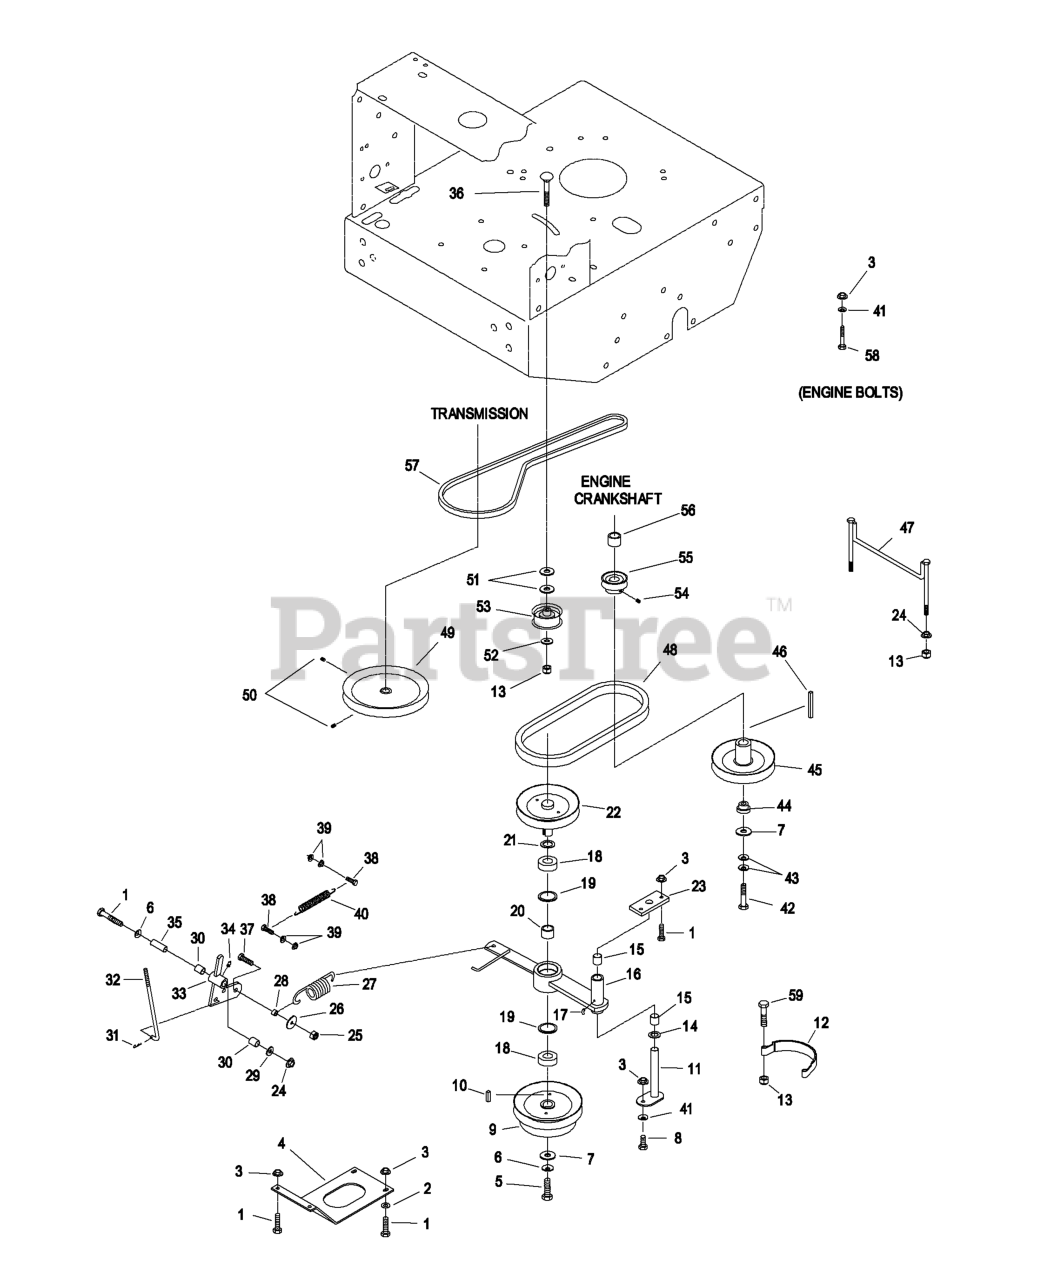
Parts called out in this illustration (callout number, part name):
1	SCREW-HH
2	WASHER-FLAT
4	PLATE-GUARD
5	SCRW,CAP HH
6	WASHER-BELLEVILLE
8	SCREW-HH
9	SHEAVE,6.13 W/HUB
11	WLD,PIN PIVOT
12	BAND,BRAKE BLADE
13	NUT-LOCK, NI
14	WASHER-SPACER
15	SLEEVE,BEARING
16	Arm Weldment, Clutch
17	FITTING-GREASE
18	BEARING,CLUTCH SHAFT
19	RING-SNAP
20	SPACER,CLUTCH BEARING
21	WASHER-SPACER
22	SHEAVE,6.13 W/SHAFT
23	PLATE-CLUTCH PIVOT
24	NUT-HHF, WHIZ
25	NUT-LOCK, NI
27	SPRING,BELT TENSION
28	SPACER,CLUTCH ANCHOR
29	WASHER-FLAT
30	SLEEVE-BEARING
31	PIN-COTTER
32	LINKAGE,LOWER
33	ASM,PIVOT W/BUSHINGS
34	FITTING-GREASE
35	BUSHING
36	SCREW-HH
37	SCREW-HH
38	SCREW-HH
40	SPRING,EXTENSION
41	WASHER-SPRING
42	SCREW-HH
43	WASHER-SPRING
44	BUSHING,CLUTCH KEEPER
45	SHEAVE,ENGINE
46	KEY,MACH 1/4X1/4X2-5/8
47	GUIDE - BELT
48	BELT,BLADE CLUTCH
49	SHEAVE-TRANSMISSION
50	SCREW-HSH
51	WASHER-FLAT
52	WASHER-FLAT
54	SCREW-SET
55	SHEAVE-TRANSMISSION
56	SPACER,CRANKSHAFT
57	BELT,TRANS DRIVE
58	SCREW-HH
59	SCREW-HH
